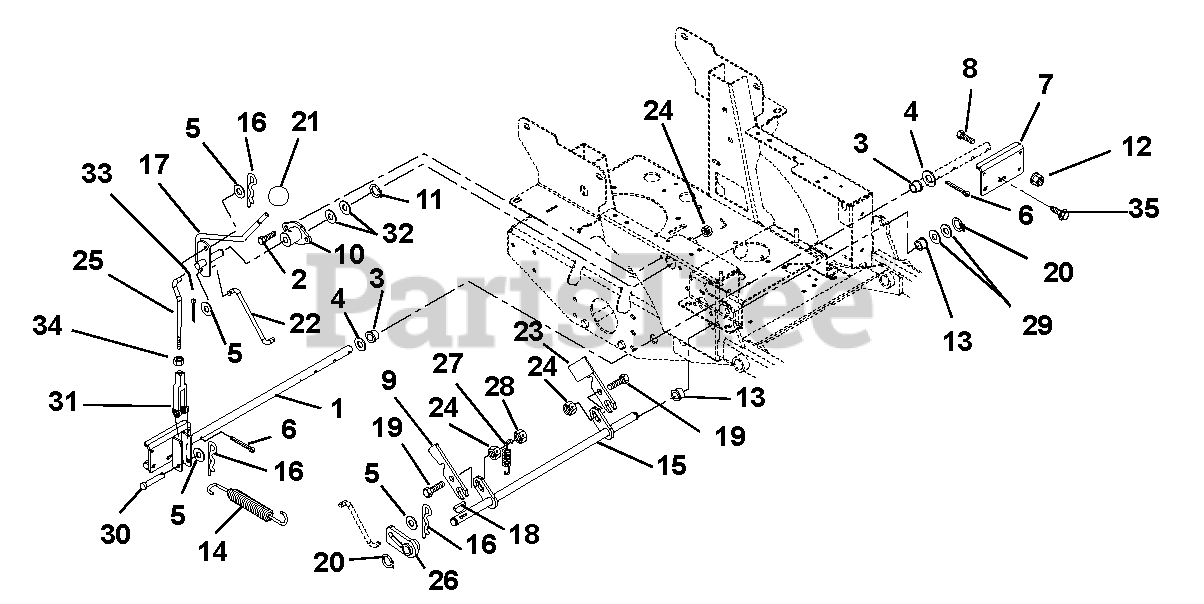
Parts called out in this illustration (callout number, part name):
1	Weldment, Brake Shaft
2	Bolt, Hex .31-18 x 1.00
3	Bushing, Flange .762 x 1.00 x .58 x 1.48 Nylon
4	Washer, Flat Steel .755 x 1.375 x .062
5	Washer, Flat Steel .406 x .812 x .065
6	Pin, Cotter .12 x 1.00 Extended Prong Square Cut
7	Paddle, Brake
8	Bolt, Hex .25-20 x 1.5
9	Slide, Interlocking Brake
10	Bushing, Flange
11	Ring, Retaining External .625 x .05
12	Nut, Nyloc Flange .25-20
13	Bushing, Flange .515 x .75 x .745 x 1.00
14	Spring, Engine Transmission
15	Weldment, Mechanical Brake
16	Pin, Hair
17	Weldment, Brake Actuating
18	Key, Woodruff .13 x .63
19	Bolt, Round Head Square Neck .31-18 x 1.25
20	Ring, Retaining External .50 x .05
21	Knob, Steering Lock
22	Linkage, Brake Actuating
23	Interlock, Safety Switch
24	Nut, Nyloc Flange 5/16-18
25	Linkage, Brake Compact-Z
26	Weldment, Parking Brake Hub
27	Spring, Tension .061 x .50 x 3.0
28	Nut, Locking Center .31-18
29	Washer, Flat Steel .505 x 1.00 x .062
30	Pin, Clevis .37 x 1.75
31	Clevis, .38-24 Adjustable Swivel
32	Washer, Flat Steel .630 x 1.250 x .062
33	Pin, Cotter .09 x .75 Extended Prong Square Cut
34	Nut, Jam .375-24
35	Screw, Tapping .31-18 x .75 Hex Washer Head Thread Rolling
